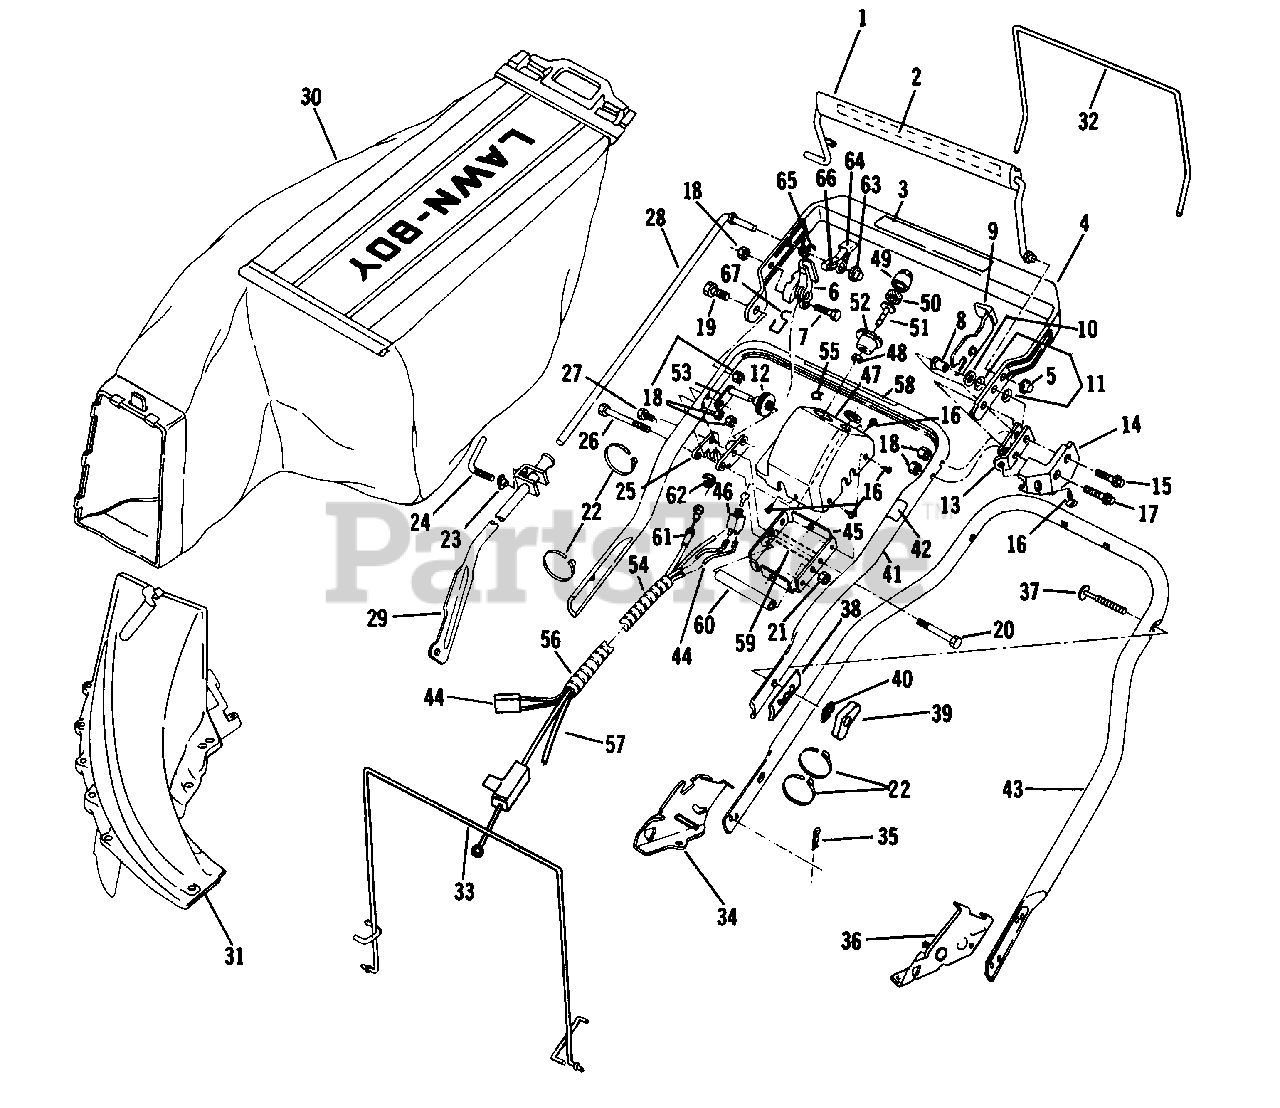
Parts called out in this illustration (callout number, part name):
1	Control Lever Assembly-Bail
2	Decal-Blade Control
3	Decal-Drive Control
4	Top Handle and Grip Assembly
5	Pushnut
6	Cam-Clutch Cont. Bail
7	Bolt-Hex
8	Spacer-Flanged
9	Lever-Lockout
10	Washer-Plain
11	Washer-Spring
12	Pulley
13	Down-Stop
14	Guard-Lockout
15	Bolt-Shoulder
16	Screw
17	Bolt-Shoulder-L.H.
18	Locknut
19	Bolt-Shoulder-R.H.
20	Screw-Hex Hd. Cap.
21	Nut-Hex Jam
22	Tie Strap
23	Nut-Cont. Lvr. Clamp
24	Lever-Rod Clamp
25	Bracket-Clutch Cable
26	Screw
27	Screw-Clutch Cable Brkt.
28	Rod-Control
29	Control Lever Assembly
30	Bag and Deflector Assembly
31	Chute Assembly
32	Hanger-Rear
33	Hanger Assembly-Front
34	Bracket-Handle-R.H.
35	Hair Pin
36	Bracket-Handle L.H.
37	Screw
38	Bracket-Rear Hanger
39	Knob
40	Washer-Curved
41	Handle Section-Center
42	Decal-Drive Lockout
43	Handle Section-Bottom
44	Wire Harness Assembly
45	Plate-Cover Assembly
46	Switch Assembly
47	Cover
48	Locknut
49	Primer Bulb
50	Filter
51	Primer Base
52	Cup
53	Pivot Bracket-Pulley
54	Spiral Tubing
55	Decal
56	Spiral Tubing
57	Tubing-Primer
58	Decal-Starting Inst.
59	Spacer
60	Spacer
61	Control Cable Assembly
62	Ring-Retainer
63	Pushnut
64	Decal-Stop-Latch Lever
65	Spring-Torsion
66	Stop-Latch Lever
67	Retainer-Cable to Cam
